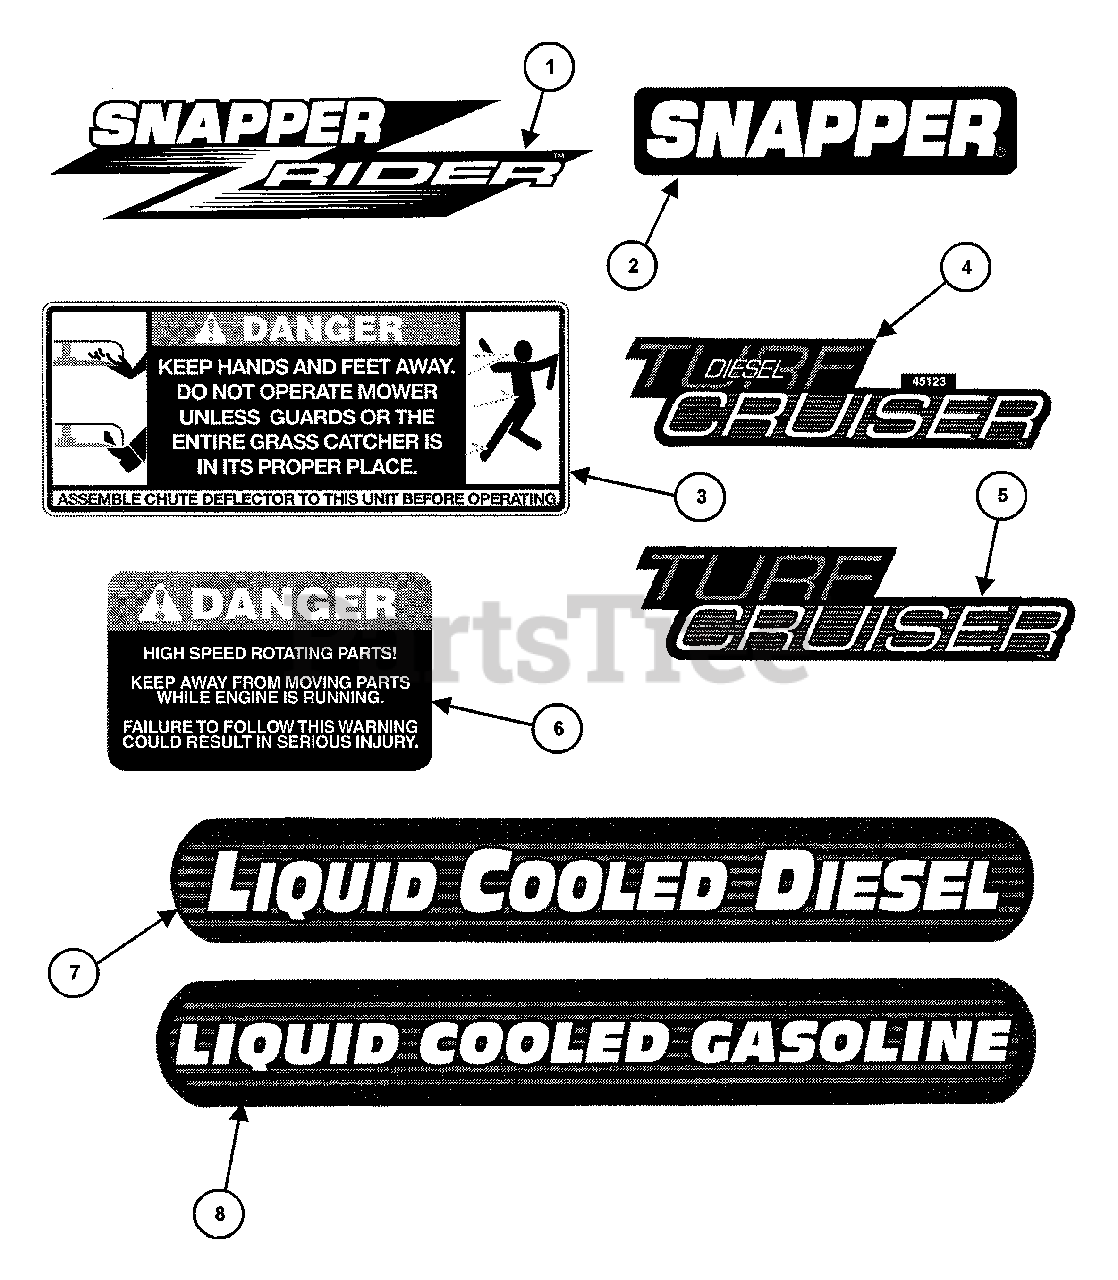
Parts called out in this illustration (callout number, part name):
1	DECAL, Snapper Z-Rider (12-1/2" Long)
2	DECAL, Snapper (7-5/16" Long)
3	DECAL, Danger Guard/Catcher
4	DECAL, Turf Cruiser-OFD
5	DECAL, Turf Cruiser-OFG
6	DECAL, Danger Rotating Parts
7	DECAL, Liquid Cooled Diesel
8	DECAL, Liquid Cooled Gas
